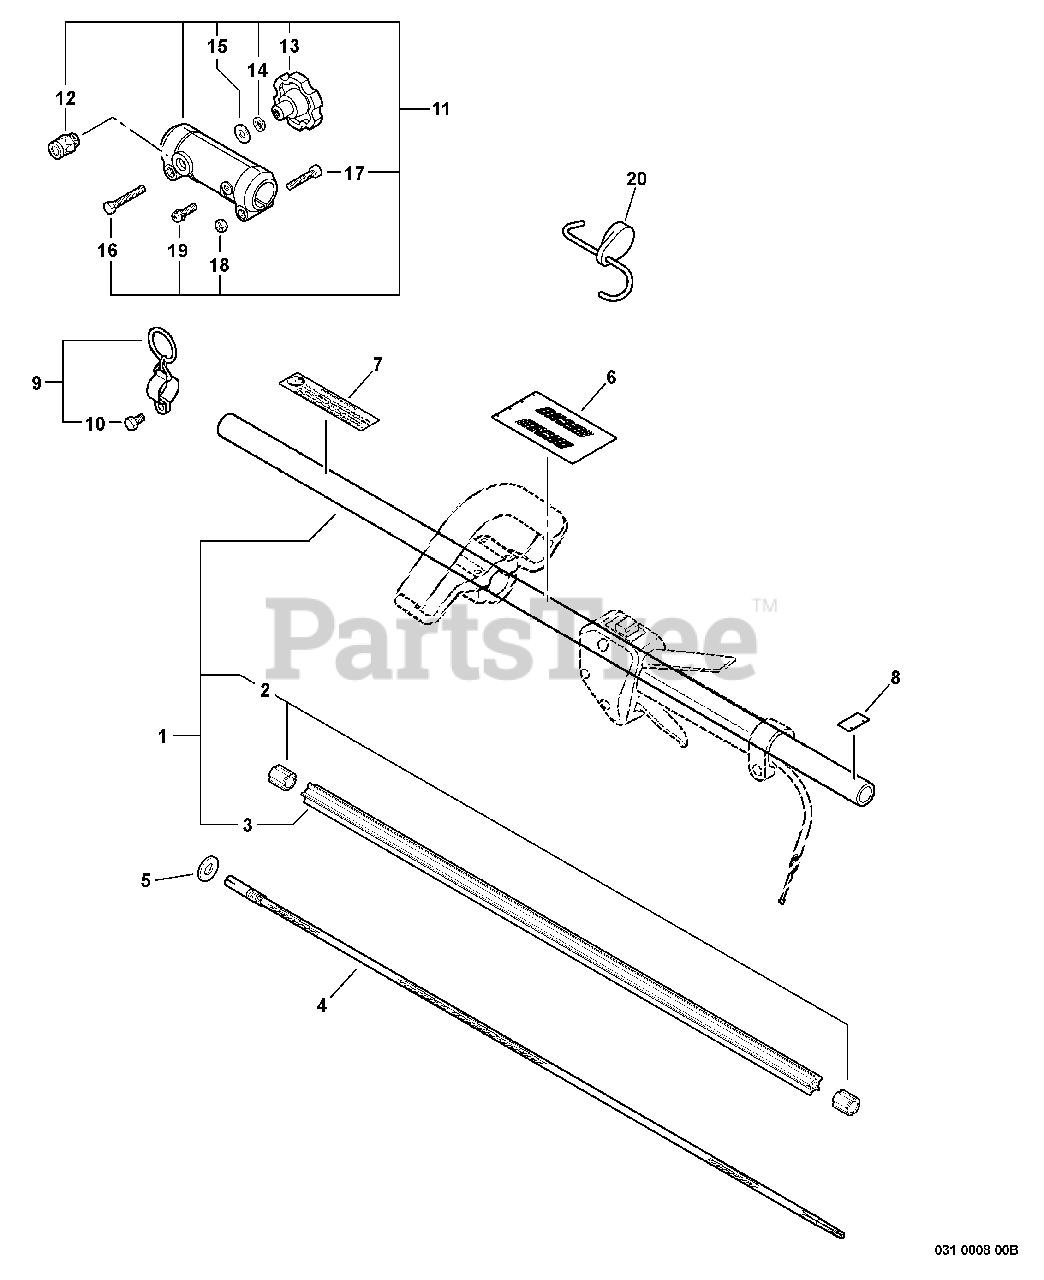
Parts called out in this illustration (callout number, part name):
1	MAIN PIPE ASSY
3	LINER - FLEXIBLE
4	DRIVESHAFT - FLEXIBLE
6	LABEL, HANDLE LOCATION
7	LABEL, CAUTION
8	LABEL - ALIGNMENT
9	HANGER SET, HARNESS
10	BOLT 5×12
11	COUPLER ASSY
12	LATCH ASSY
13	KNOB
14	WASHER, SPRING 5
15	WASHER, FLAT 5.5×10×0.8
16	BOLT 5×35 SP
17	BOLT 5×30
18	NUT M5
19	SCREW 5×14
20	HANGER, ATTACHMENT
